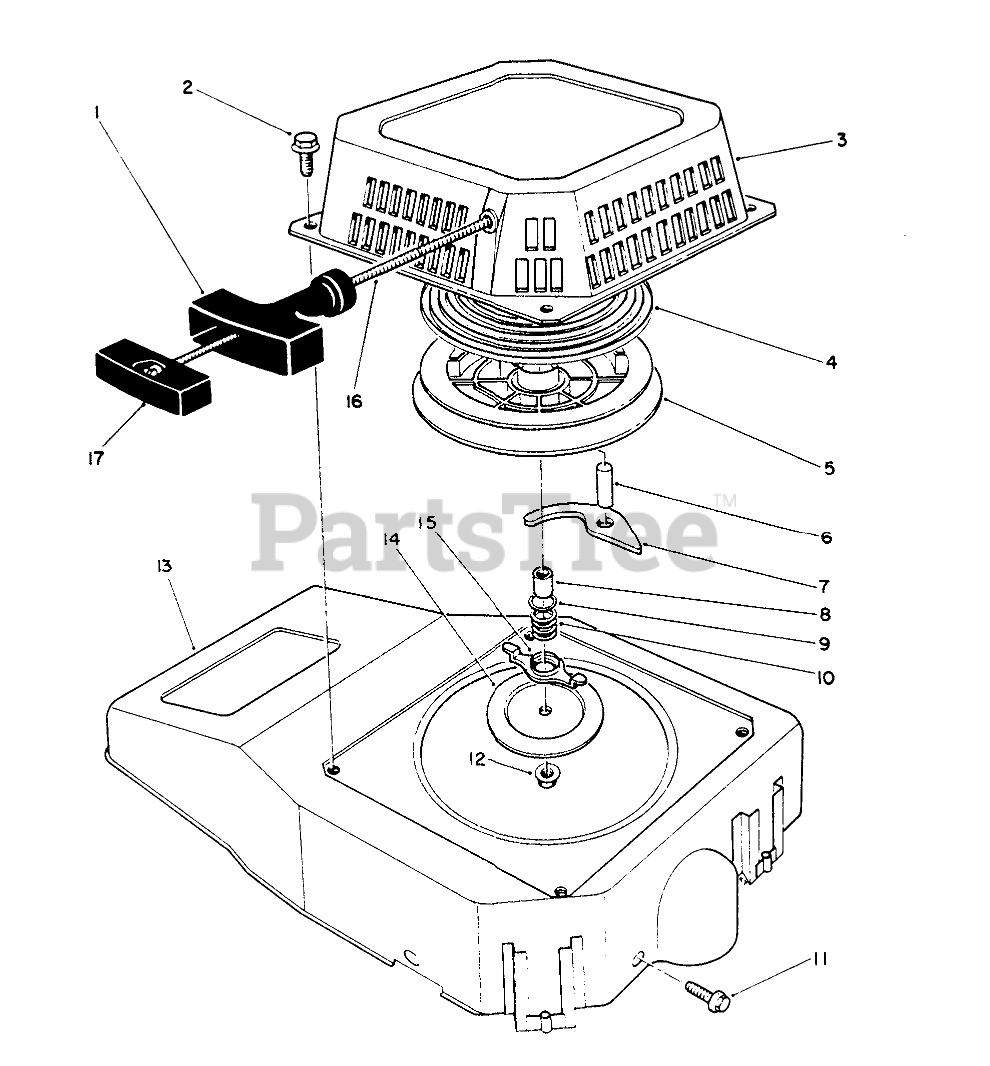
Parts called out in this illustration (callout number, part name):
1	HANDLE
2	SCREW-HHF
3	Case-Recoil
4	SPRING
8	Spacer
9	WASHER
10	Spring-Friction
13	SHROUD
14	PLATE
15	Guide-Paw
16	ROPE-STARTER
17	RETAINER HANDLE
